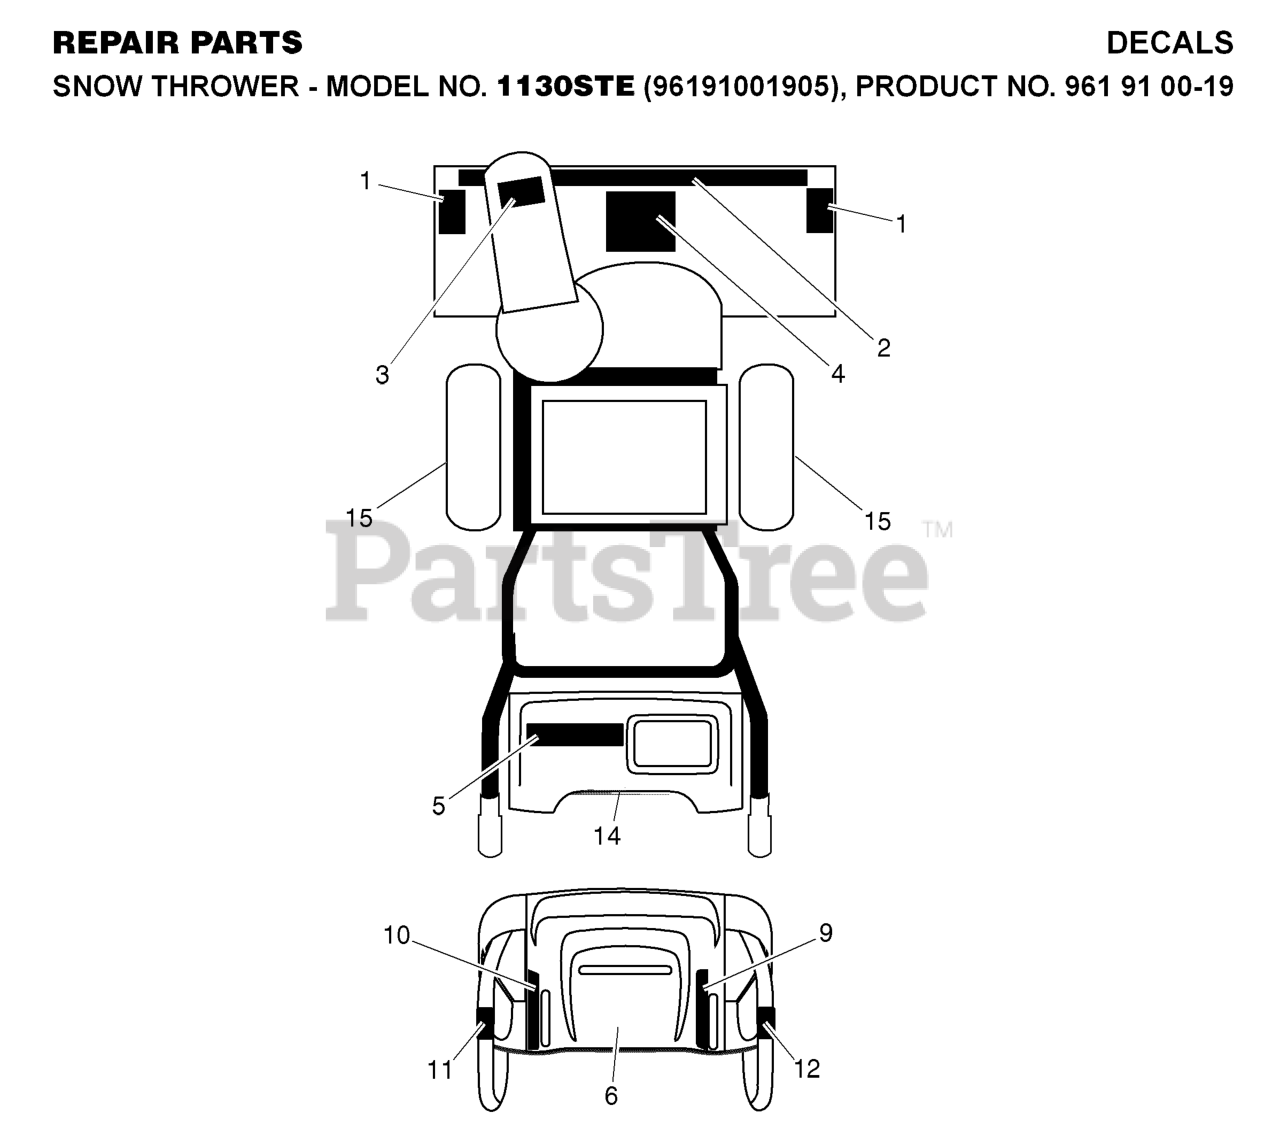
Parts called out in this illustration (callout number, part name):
1	DECAL.AUGER.SAFETY.
3	DECAL.CHUTE.SAFETY.
4	DECAL.AUGER."
6	DECAL.CONSOLE.INSTRUCTION
10	DECAL.REM.DEFLECTOR.LT
11	DECAL.POWER.STEER.LT.TRIG.INT
12	DECAL.POWER.STEER.RT.TRIG.INT
14	DECAL.FENDER
15	DECAL.BELT.GUARD.
